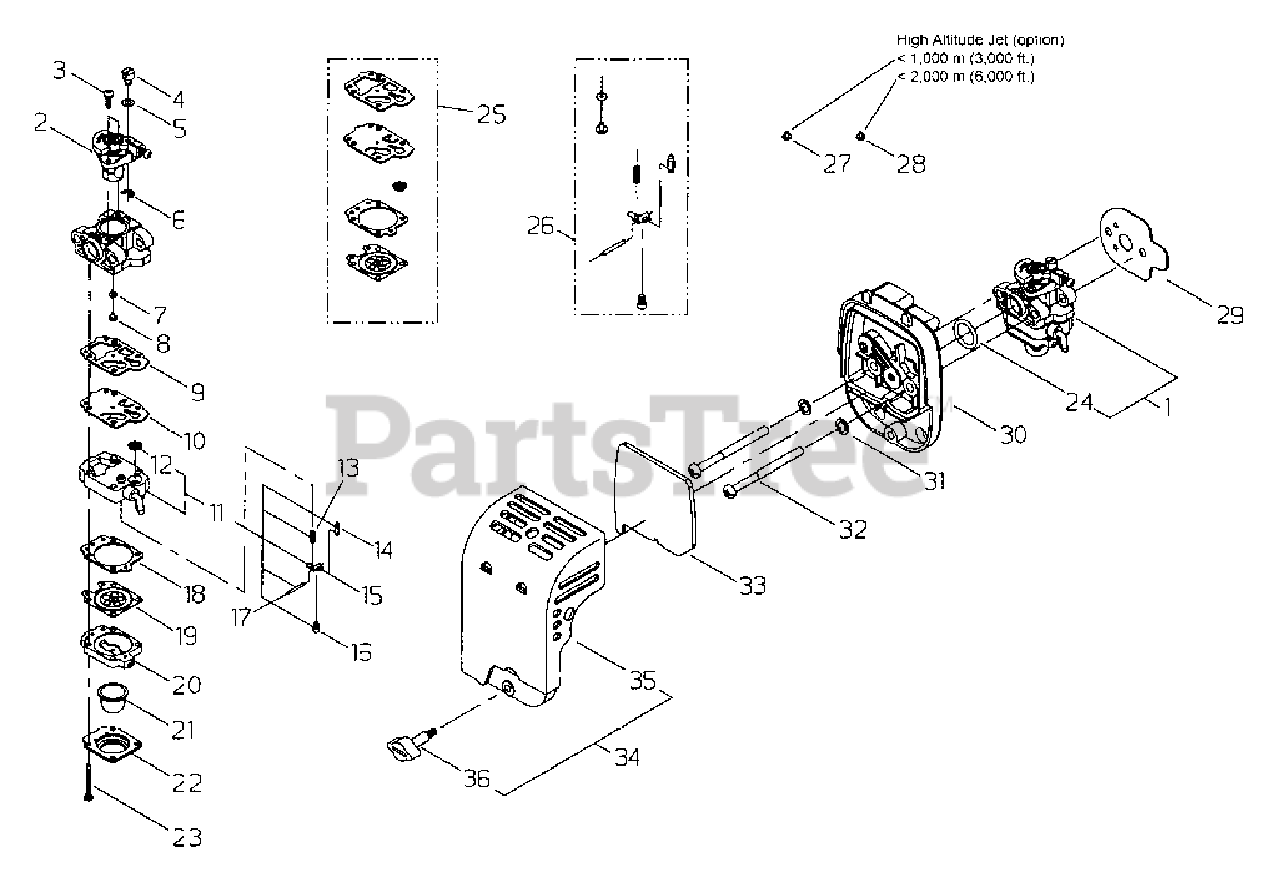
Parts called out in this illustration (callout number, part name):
1	CARBURETOR
2	THROTTLE VALVE ASSY
3	SCREW
4	SWIVEL
5	WASHER
6	RING, RETAINING
7	GASKET, PUMP
8	JET, MAIN
9	GASKET, PUMP
10	DIAPHRAGM, PUMP
11	PUMP BODY ASSY
12	STRAINER
13	SPRING, METERING LEVER
14	VALVE, INLET NEEDLE
15	LEVER, METERING
16	SCREW, METERING LEVER PIN
17	PIN, METERING LEVER
18	GASKET, METERING
19	DIAPHRAGM, METERING
20	BASE, PURGE
21	BULB, PURGE
22	RETAINER, PURGE BULB
23	SCREW, PUMP COVER
24	O-RING - 15
25	DIAPHRAGM/GASKET KIT
26	INLET NEEDLE VALVE KIT
27	JET, MAIN - 1000M
28	JET, MAIN - 2000M
29	GASKET
30	CASE, AIR FILTER
31	WASHER - 5
32	SCREW - 5X60
33	FILTER, AIR
34	AIR FILTER COVER ASSY
35	COVER, AIR FILTER
36	THUMBSCREW
